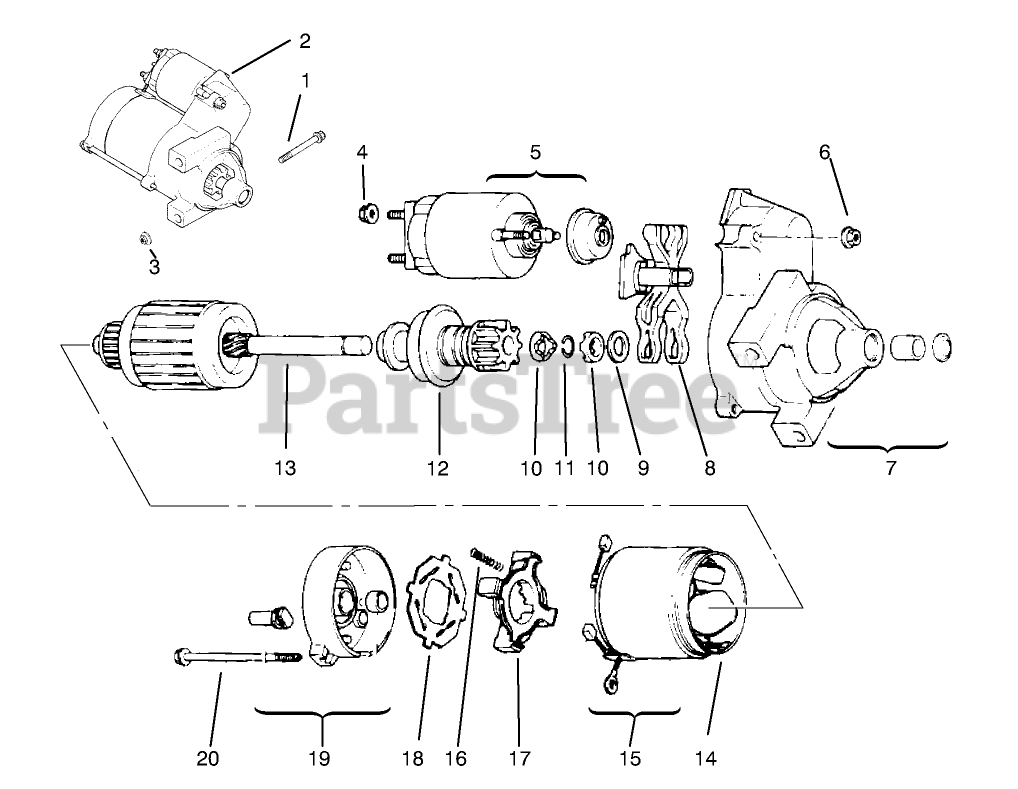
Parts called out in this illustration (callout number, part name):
1	Screw M8x1.25x80 (Only On: 72103, 72083)
2	Starter-Solenoid Shift (Incl. Ref. # 4-20)
4	Nut
5	Solenoid
6	Nut Starter
7	Cap-Drive End
8	Lever Starter Drive
9	Washer-Thrust (Only On: 72103, 72083)
10	Nut-Stop Collar
11	Ring-Retainer
12	Drive-Pinion
13	Armature-Starter
14	Frame
15	Kit-Brush (Incl. Ref. # 16)
16	Spring-Brush
17	Holder-Brush
18	Insulator
19	Cap-Commutator End
20	Bolt
